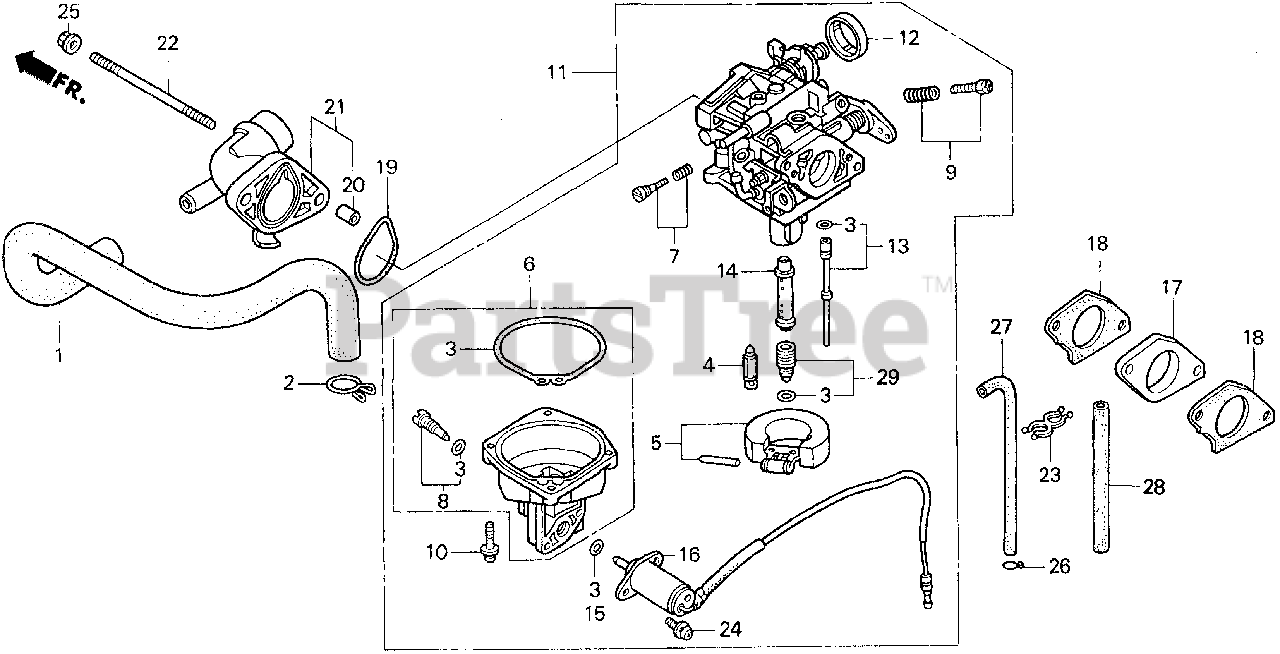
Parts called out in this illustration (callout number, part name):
1	TUBE, BREATHER
2	CLIP, BREATHER TUBE
3	GASKET SET
4	VALVE SET, FLOAT
6	CHAMBER SET, FLOAT
8	SCREW SET, DRAIN
10	SCREW-WASHER
11	CARBURETOR ASSY. (BG23A B)
12	CAP, CHOKE LEVER DUST
13	JET SET (#48)
14	NOZZLE, MAIN
15	O-RING (5.8X1.9)
16	VALVE ASSY., SOLENOID
17	INSULATOR, CARBURETOR
18	GASKET, CARBURETOR
19	GASKET, AIR CLEANER
20	COLLAR A, AIR CLEANER
21	ELBOW, AIR CLEANER
22	BOLT, STUD (6X108)
23	CLIP, WIRE HARNESS
24	SCREW-WASHER (5X12)
25	NUT, FLANGE (6MM)
26	CLIP, TUBE (B8)
27	BULK HOSE, VACUUM (3.5X1000) (3.5X600)
28	BULK HOSE, VACUUM (4.5X1000) (4.5X450)
29	JET SET, MAIN (#90)
29	JET SET, MAIN (#92)
29	JET SET, MAIN (#95)
